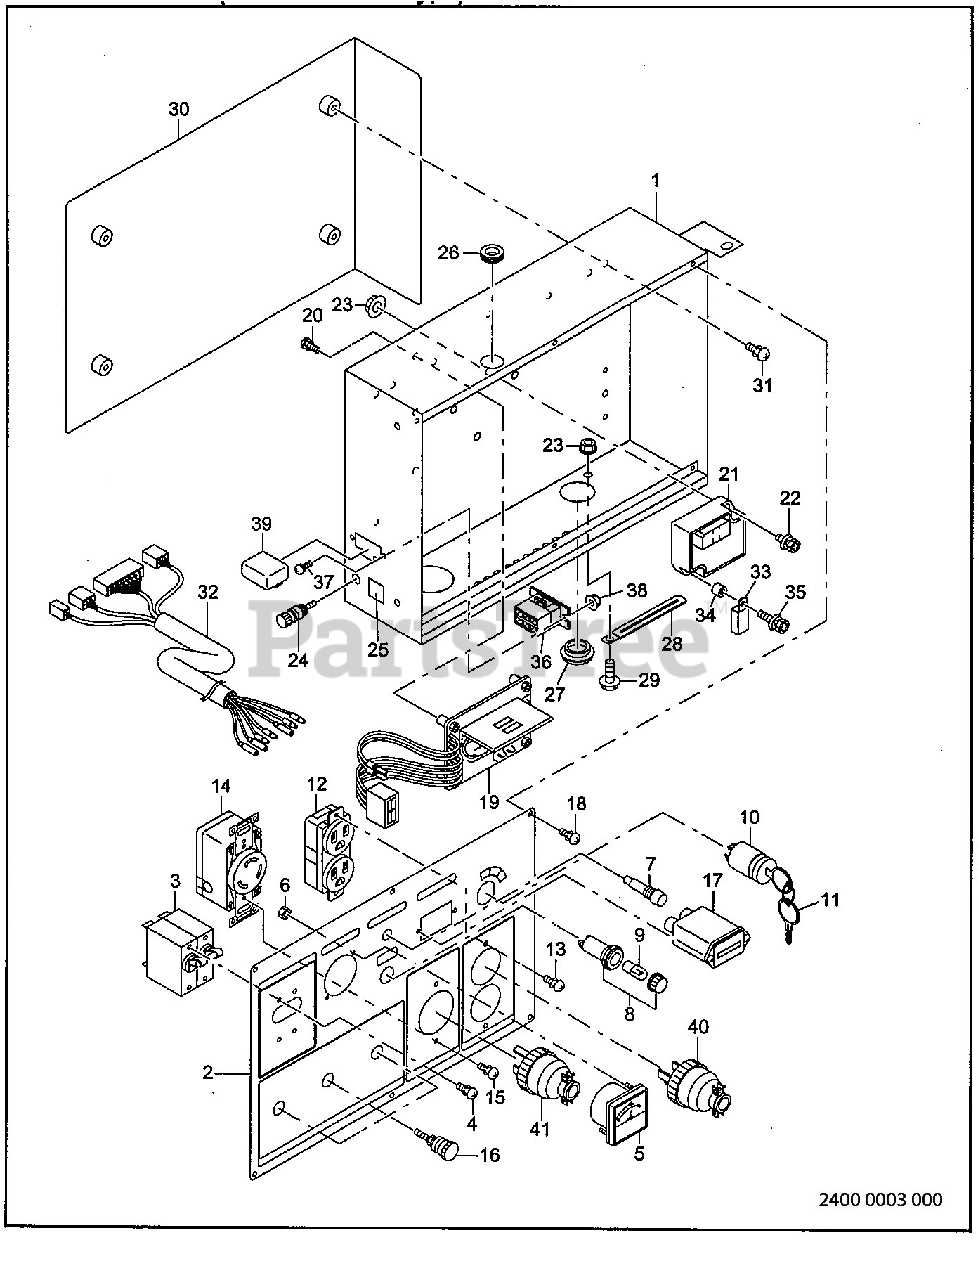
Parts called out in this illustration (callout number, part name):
1	CONTROL BOX ASSY
1	CONTROL BOX UNIT
2	CONTROL PANEL ASSY
2	CONTROL PANEL
3	BREAKER (2P-42A)
4	SCREW and WASHER ASSY
8	LAMP (OIL)
9	LAMP (18V·0.11A)
10	KEY SWITCH
12	AC RECEPTACLE (125V-15A)
13	SCREW and WASHER ASSY
14	AC RECEPTACLE (250V·30A, TWIST LOCK)
15	SCREW and WASHER ASSY
16	TERMINAL
17	HOUR METER
18	SCREW and WASHER ASSY
19	AVR ASSY
20	SCREW and WASHER ASSY
21	ECU (O/S & R/C) ASSY
21	ECU{O/S & R/C) ASSY
22	SCREW and WASHER ASSY
29	FLANGE BOLT
31	SCREW and WASHER ASSY
32	WIRE ASSY
35	SCREW
36	CONNECTOR (6P)
37	SCREW and WASHER ASSY
40	AC PLUG (250V-15A)
41	AC PLUG (250V-30A)
